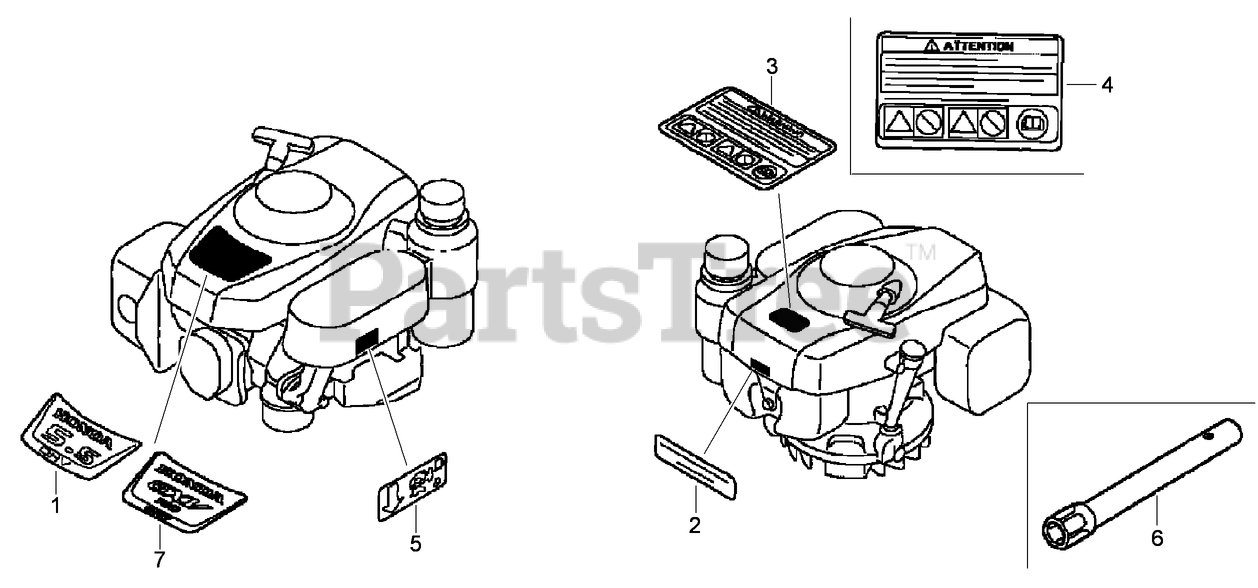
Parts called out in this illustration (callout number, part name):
1	MARK, EMBLEM (SERIAL NUMBERS UP TO 1036455)
2	MARK-MANUFACTURER
3	MARK-CAUTION, OPERATOR (ENGLISH)
3	MARK-CAUTION, OPERATOR (FRENCH)
4	MARK-CAUTION, OPERATOR (PICTOGRAPH)
5	MARK-CAUTION, FUEL PETCOCK
6	Wrench-Box (P21)
7	MARK, EMBLEM (GXV160) (SERIAL NUMBERS FROM 1036456)
